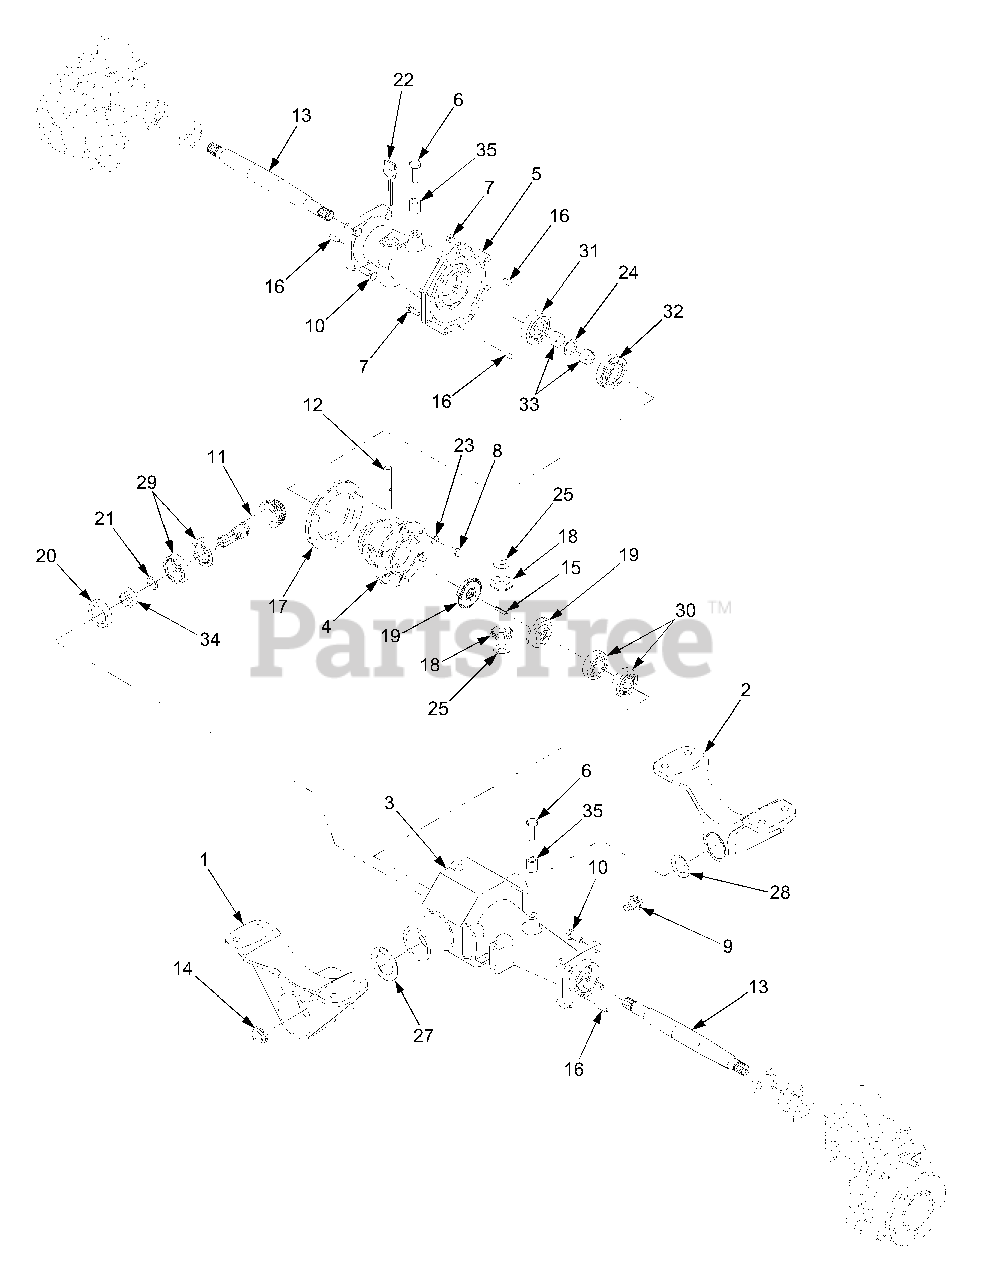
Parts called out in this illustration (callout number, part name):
1	Bracket, Front Axle Mtg. - Rear
2	Bracket, Front Axle Mtg. - Front
3	Housing, Main Axle RH
4	Housing, Differential
5	Housing, Axle LH
6	Screw, Hex Cap, M10-1.5 x 35 GR8.8
7	Screw, Hex Cap, M8-1.25 x 25 GR8.8
8	Screw, Hex Cap, M8-1.25 x 14 GR8.8
9	Plug, Screw, M14-1.5 x .827
10	Screw, Hex Cap, M10-1.5 x 25
11	Shaft, Input, 6T
12	Shaft, Cross
13	Shaft, Axle
14	Nut, Special, 24mm
15	Pin, Roll, 5mm x 26mm
16	Pin, Dowel, 8mm x 20mm
17	Gear, Bevel, 34T
18	Gear, Miter, 10T
19	Gear, Miter, 16T
20	Seal, Oil, 52mm x 35mm x 10mm
21	O-Ring, 19mm x 3mm
22	Dipstick, Front Axle
23	Washer, Flat, .33 x .63 x .0635
24	Washer, Flat, .793 x 1.24 x .06 Hdn.
25	Washer, Special Spherical
26	Washer, Flat, .793 x 1.37 x .005
27	Washer, Thrust, 1.66 x 2.59 x .059
28	Washer, Thrust, 1.03 x 1.73 x .059
29	Bearing, Tapered Roller w/ Race
30	Bearing, Ball
31	Bearing, Ball
32	Bearing, Ball
33	Spacer, 20 x 25 x 16mm
34	Spacer, 25 x 35 x 12mm
35	Spacer, .5 x .75 x .86
